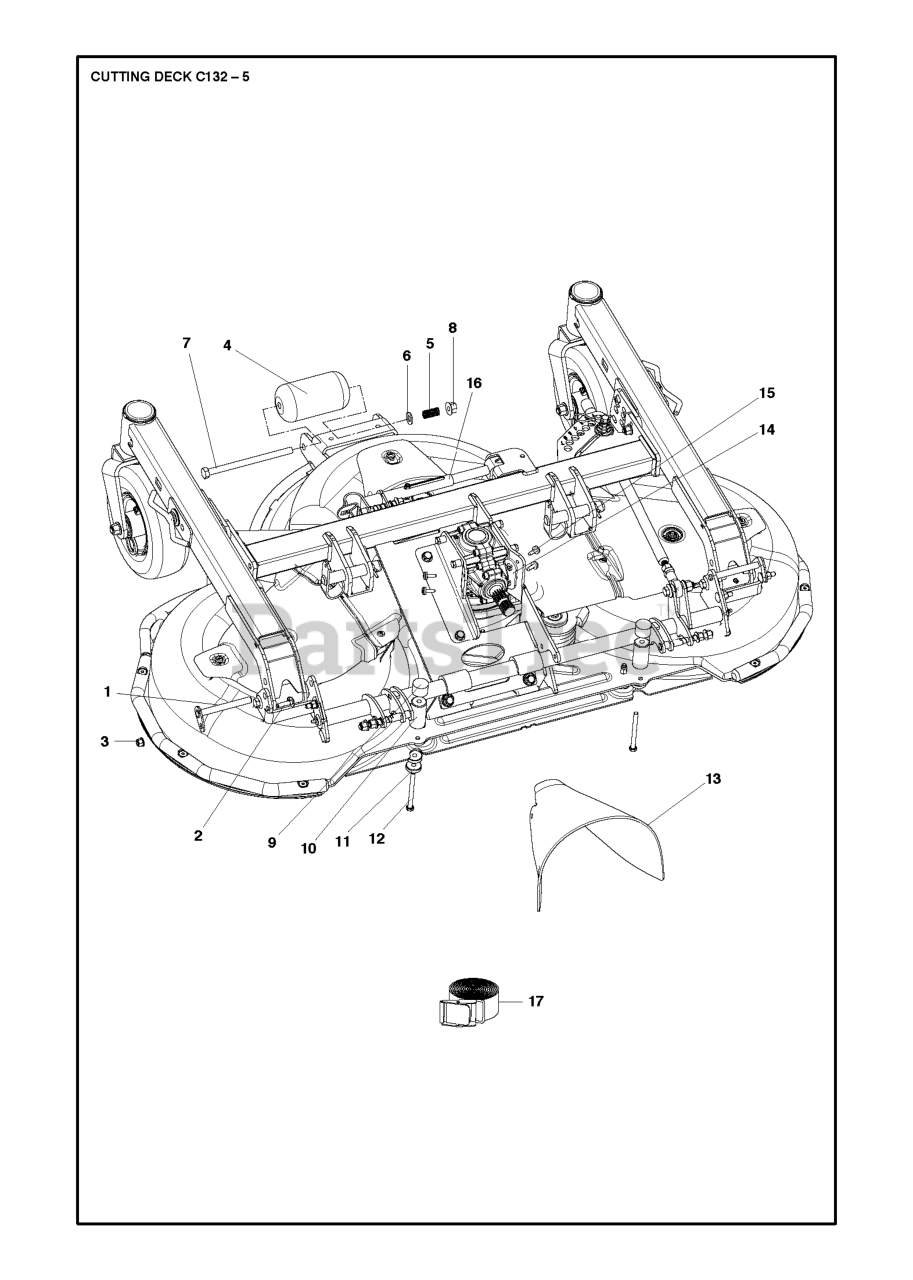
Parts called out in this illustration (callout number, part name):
3	NUT FLANGE
6	WASHER - M12
9	ANTIVIBRATION ELEMENT
